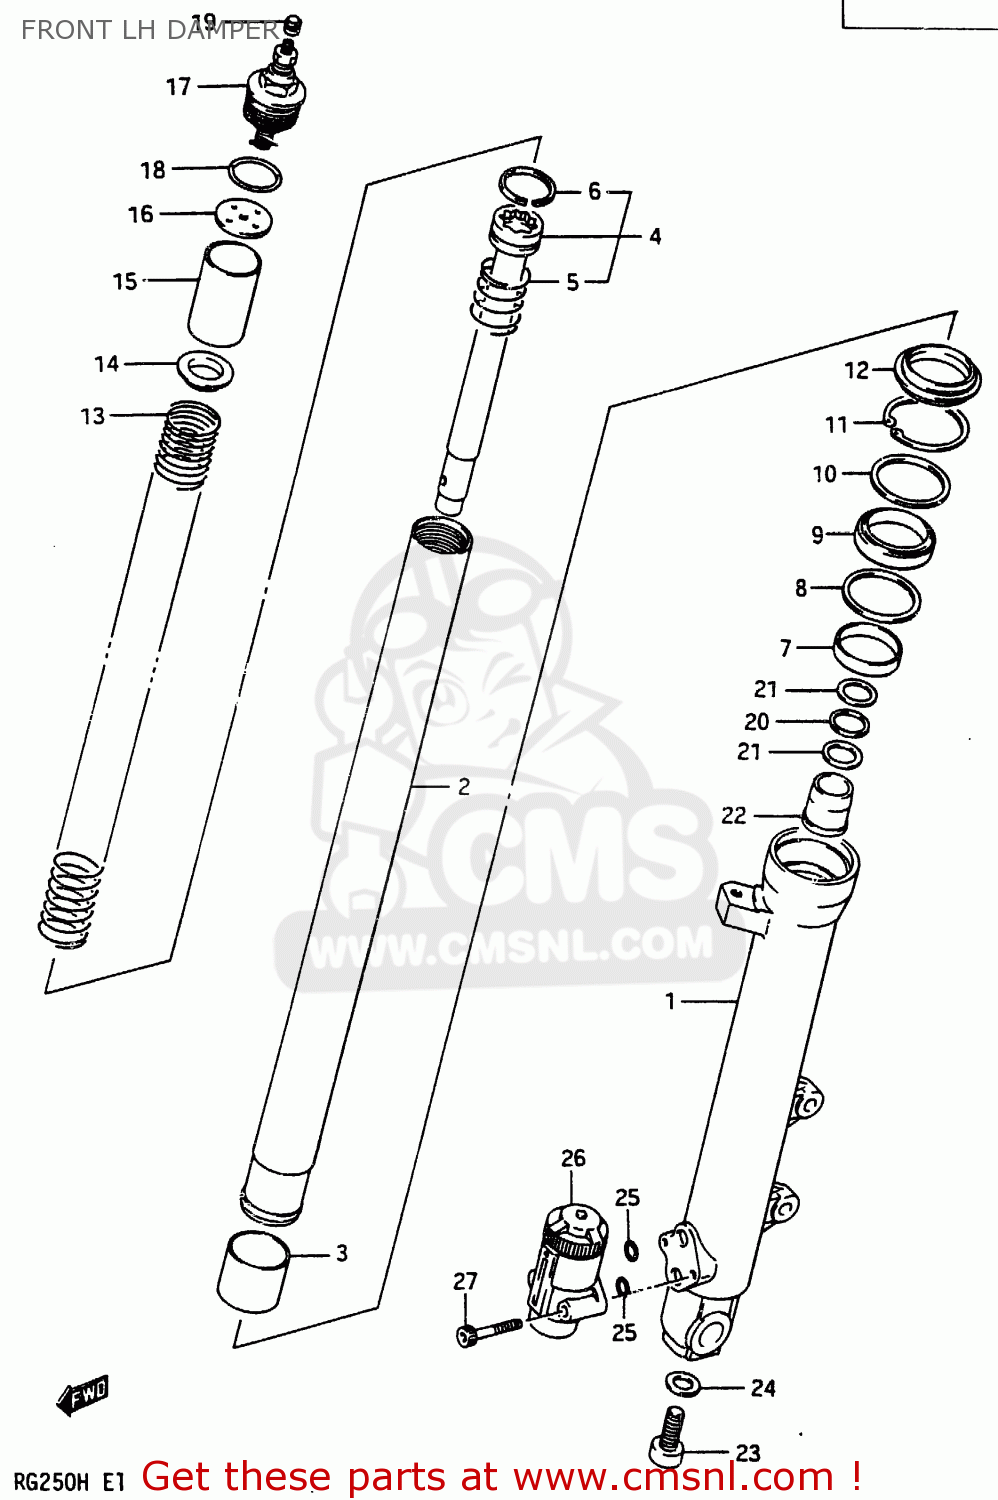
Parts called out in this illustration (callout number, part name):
1	TUBE, OUTER LH
2	TUBE, INNER
3	PISTON
4	CYLINDER
5	SPRING,REBOUND
6	RING,PISTON
7	METAL,SLIDE
8	WASHER,OIL SEAL INNER
9	SEAL,OIL
10	WASHER,OIL SEAL OUTER
11	12
12	SEAL,DUST
13	SPRING
14	GUIDE,SPRING
15	SPACER
16	WASHER
17	CAP
18	O RING
19	CAP,VALVE AIR
20	WASHER
21	SPRING,LEAF
22	PIECE,OIL LOCK
23	BOLT,FORK CYLINDER(10X25)
24	GASKET (NAS)
25	O RING
26	P.D.F. ASSY
27	BOLT
